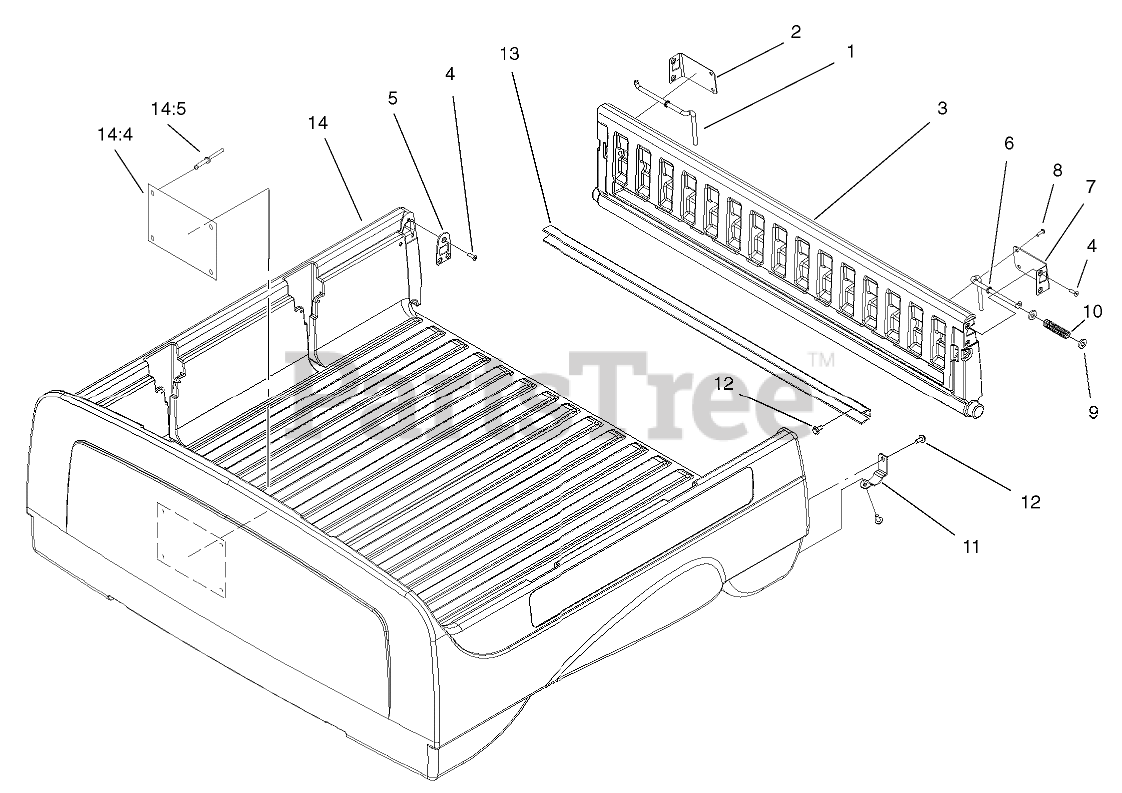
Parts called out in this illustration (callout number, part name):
1	ROD-LATCH, RIGHT
2	BRACKET-TAILGATE LATCH, RIGHT
3	TAILGATE ASM
4	SCREW
5	PLATE-STRIKER
6	ROD-LATCH, LEFT
7	BRACKET-TAILGATE LATCH, LEFT
8	SCREW
9	WASHER-LATCH
10	SPRING
11	BRACKET-PIVOT, TAILGATE
12	SCREW-HHF
13	CHANNEL-TAILGATE
14	BOX ASM
14:4	DECAL-NO RIDERS
